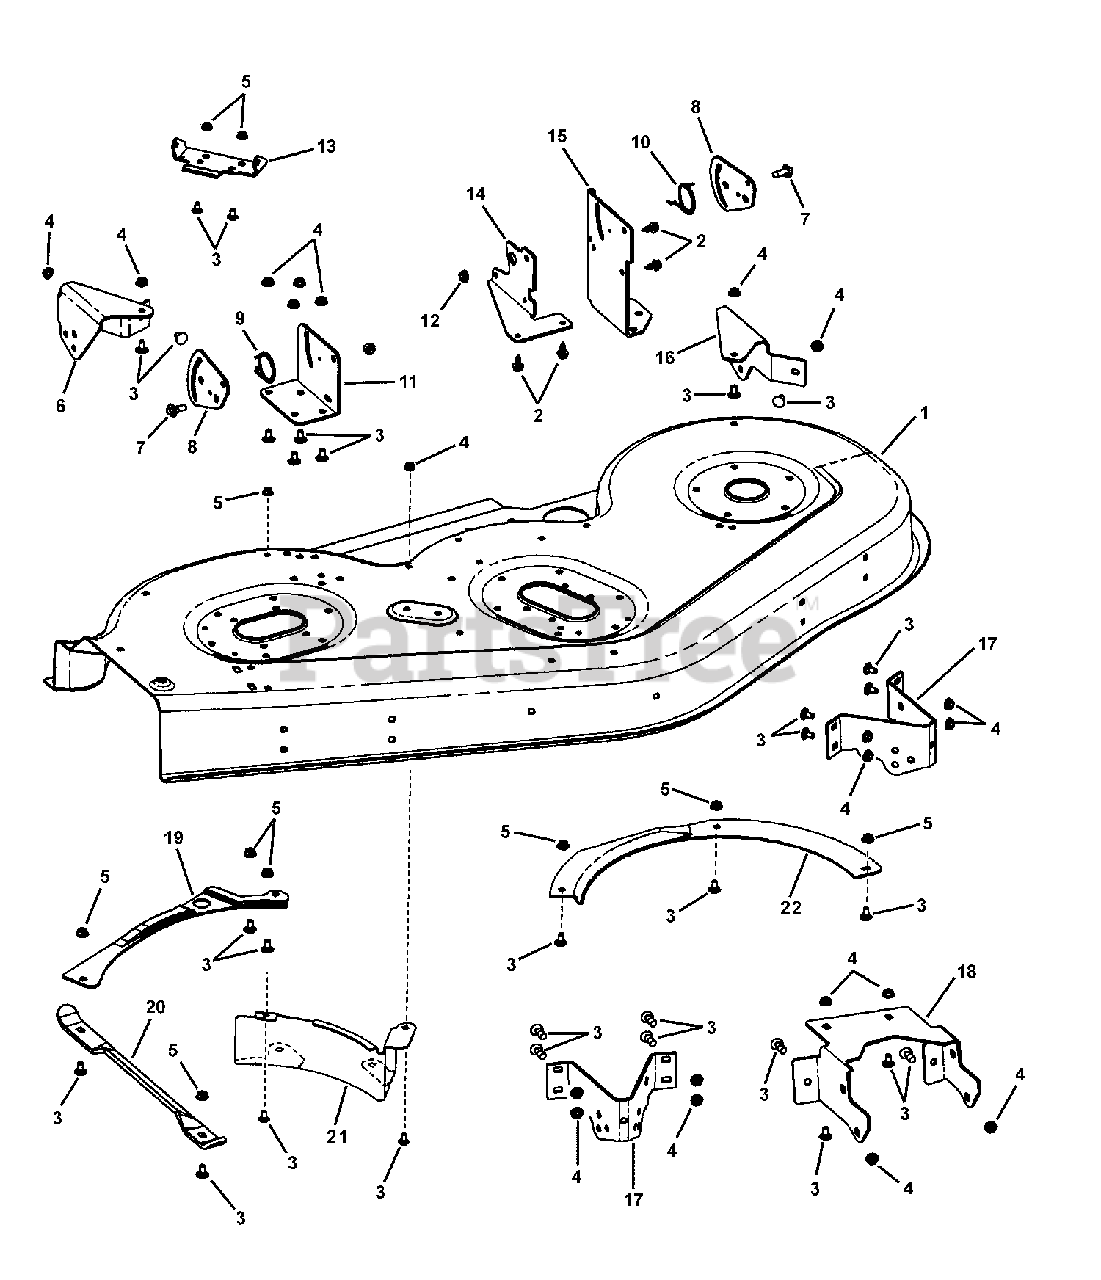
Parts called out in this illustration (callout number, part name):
1	HOUSING, 52" Mower Deck
2	CAPSCREW, 5/16-18 Hex Washer Face
3	BOLT, 5/16-18 x 5/8" Square Neck Carriage, GR 5
4	NUT, 5/16-18 Hex Flange Ser YZ
5	NUT, 5/16-18 Hex Flange Lock, NC
6	BRACKET, Gage Wheel RH Rear
7	BOLT, 3/8-16 Shoulder
8	PLATE, Suspension
9	SPRING, Torsion RH
10	SPRING, Torsion LH
11	BRACKET, Lifter RH
12	NUT, 3/8-16 Hex Flange Lock, NC
13	BRACKET, Hinge
14	BRACE, LH Lifter
15	BRACKET, Lifter LH
16	BRACKET, Gage Wheel LH Rear
17	BRACKET, Gage Wheel 52 Deck
18	BRACKET, Front Deck
19	BAFFLE, RH Bottom
20	BRACKET, Chute Support
21	BAFFLE, RH 52" Deck
22	BAFFLE, 48/52 LH Bottom
